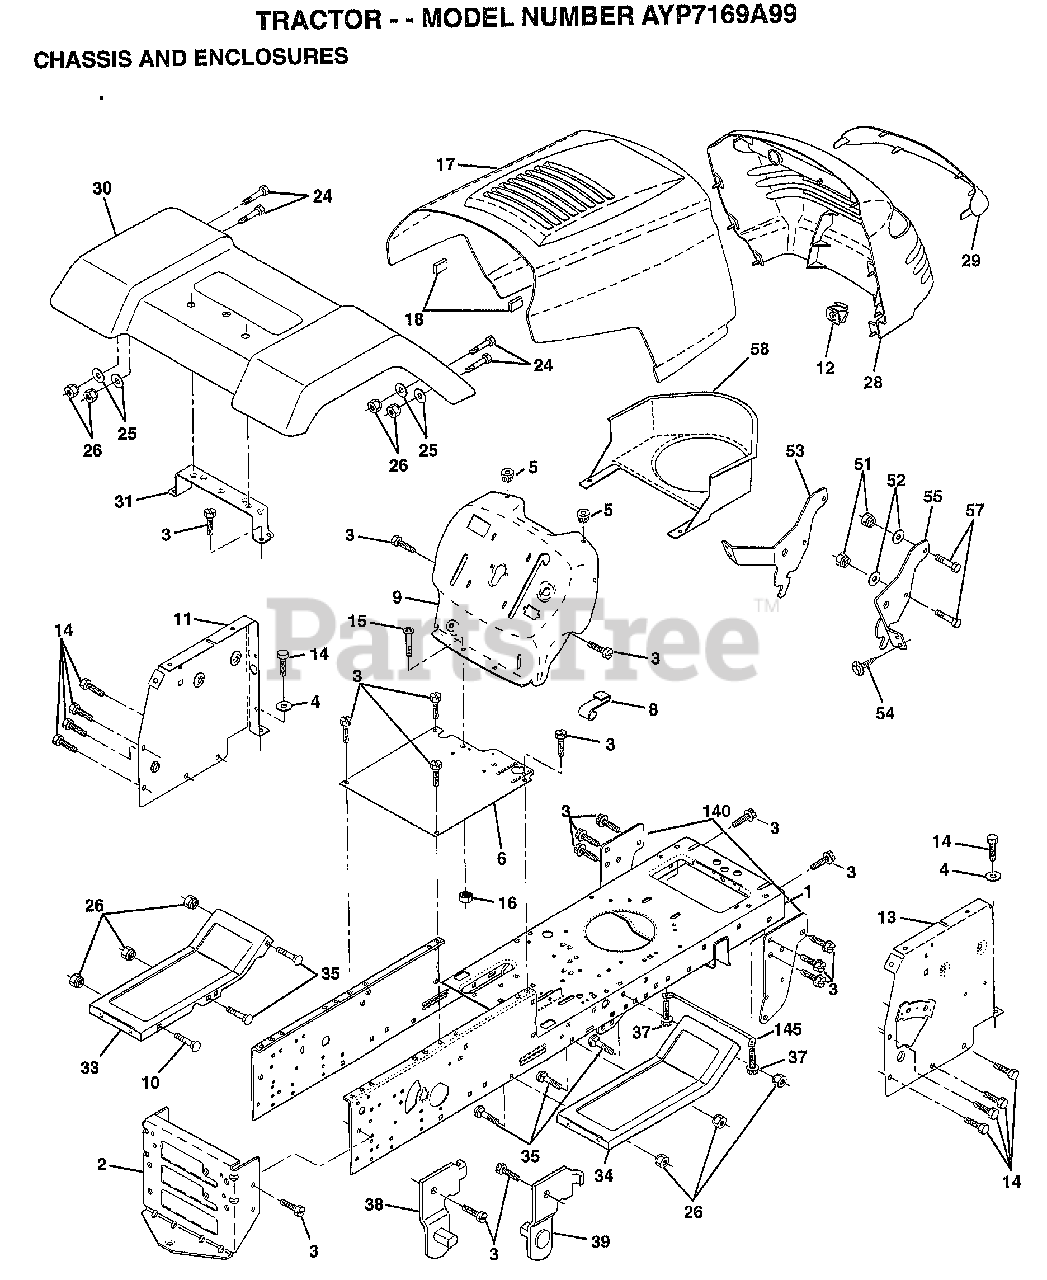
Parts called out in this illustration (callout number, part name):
1	CHASSIS.STAMPING
3	SCREW
4	WASHER
5	BUMPER-HOOD/DASH
6	SADDLE
8	CLIP.RETAINER
9	DASH SILKSCREEN
11	"PANEL-DASH,LH"
12	CLIP.TINNERMAN
14	SCREW LT
15	SCREW
17	HOOD.STEEL.ASSY
24	BOLT
25	WASHER
26	NUT
28	GRILLE-MS428
29	LENS.GRILLE.PRIVATE LABEL
30	FENDER BRACKET
31	BRKT FENDER
33	FOOTREST LH
34	FOOTREST RH
35	BOLT
37	SCREW LT
38	BRACKET ASM LH
39	BRACKET ASM RH
51	NUT
52	WASHER
53	BRACKET.GRILLE.LH
54	SCREW.HEX.WS.HD
55	BRACKET.GRILLE.RH
58	AIR DUCT
140	BRKT SUSPENSION
145	"ROD POVOT,CHASSIS"
